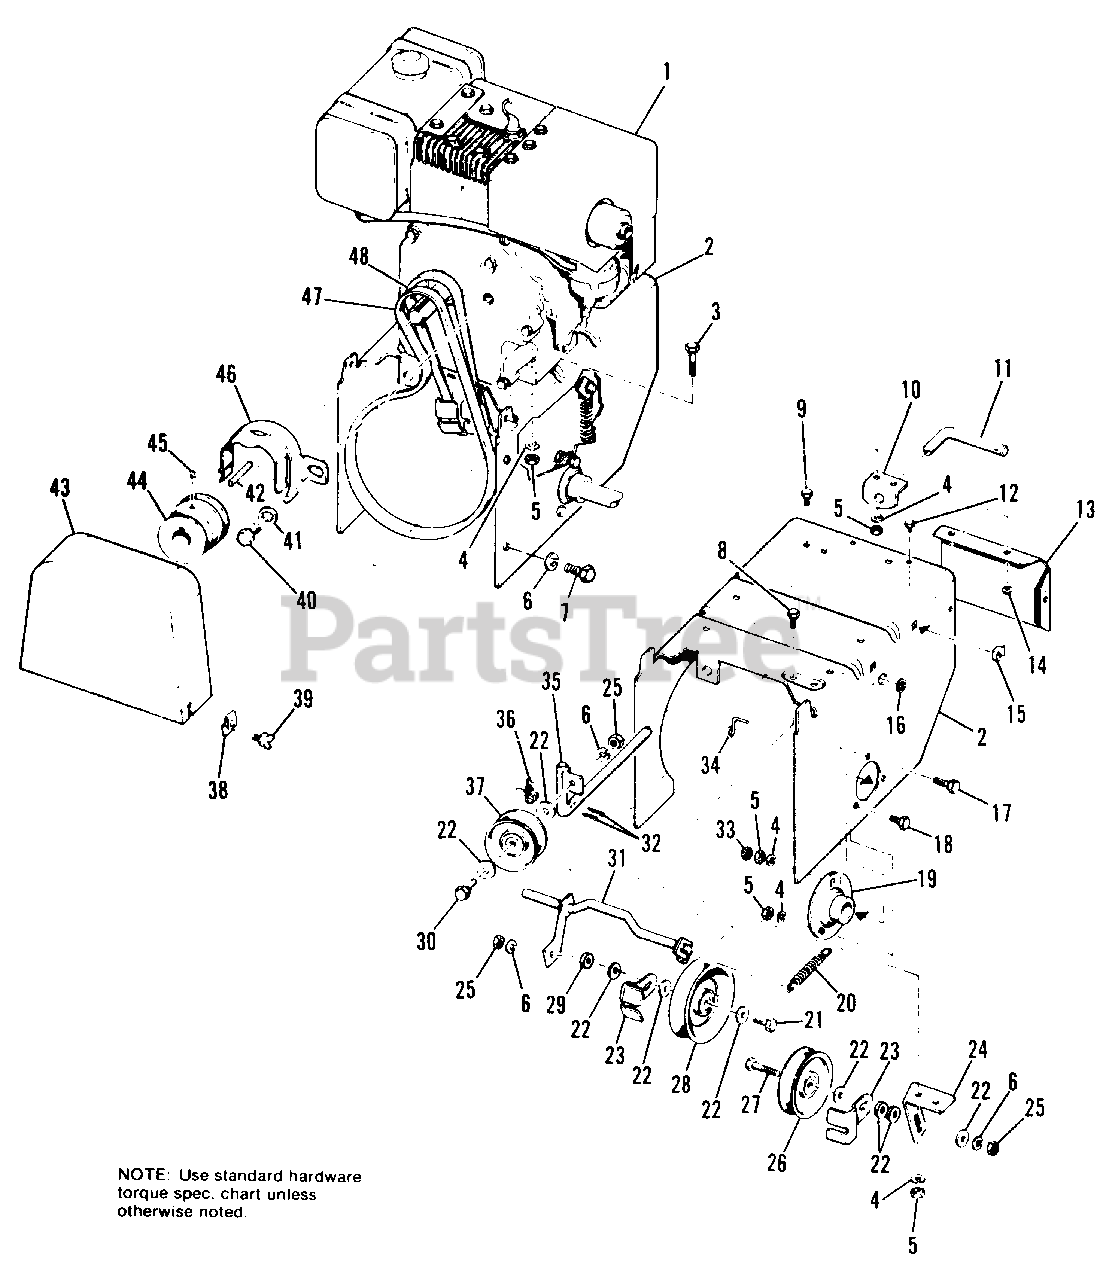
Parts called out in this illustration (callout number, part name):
2	ENGINE BASE & FRAME (990372 Only)
2	ENGINE BASE & FRAME (990430 Only)
2	ENGINE BASE & FRAME (990560 Only)
3	CAPSCREW, Hex Hd., 5/16-18 x 1-3/4
4	LOCKWASHER, 5/16
5	NUT, Hex, Full, 5/16-18
6	LOCKWASHER, 3/8
7	CAPSCREW, Hex Hd., 3/8-16 x 5/8
8	CAPSCREW, Hex Hd., 5/16-18 x 1-1/4
9	CAPSCREW, Hex Hd., 5/16-18 x 5/8
10	BRACKET, Angle
11	ROD ASSY., CLUTCH Auger
12	SCREW, Hex Hd., Self Tapping, #14AB x 5/8
13	COVER, Black (990372 Only)
13	COVER, Back (990430 & 990560 Only)
14	NUT, Speed
15	NUT, Speed, 5/16-18
16	RING, Retaining
17	CAPSCREW, Hex Hd., 5/16-18 x 1 (990372 & 990430 Only)
17	CAPSCREW, Hex Hd., 3/8-16 x 1-1/4 (990560 Only)
18	CAPSCREW, Hex Hd., 5/16-18 x 3/4 (990372 & 990430 Only)
18	CAPSCREW, Hex Hd., 3/8-16 x 1 (990560 Only)
19	BEARING, Ball (990372 & 990430 Only)
19	BEARING, Ball (990560 Only)
20	SPRING
21	CAPSCREW, Hex Hd., 3/8-16 x 1-3/4
22	WASHER, Plain, 5/16
23	GUARD, Belt
24	BRACKET, Idler
25	NUT, Hex, Full, 3/8-16
26	PULLEY, Idler
27	CAPSCREW, Hex Hd., 3/8-16 x 1-1/2
28	PULLEY, Idler
30	CAPSCREW, Hex Hd., 3/8-16 x 1-1/4
31	PIVOT ASSY., Clutch
32	PIN, Cotter, 5/32 x 1
33	LOCKNUT, Hex, 5/16-18 (990372 & 990430 Only)
33	LOCKNUT, Hex, 3/8-16 (990560 Only)
35	ROD ASSY., Clutch, Auger
36	SPRING, Torsion
37	PULLEY, Idler
38	NUT, Speed, 5/16-18
39	SCREW, Thumb, 5/16-18 x 3/4
40	CAPSCREW, Hex Hd., 1/2-20 x 3/4
41	LOCKWASHER, Int, 1/2
43	COVER, Engine Pulley
44	PULLEY, Engine
45	SETSCREW, 5/16-18 x 3/8
46	GUARD, Belt
47	V-BELT (Auger Drive)
48	V-Belt (Transmission Drive)
